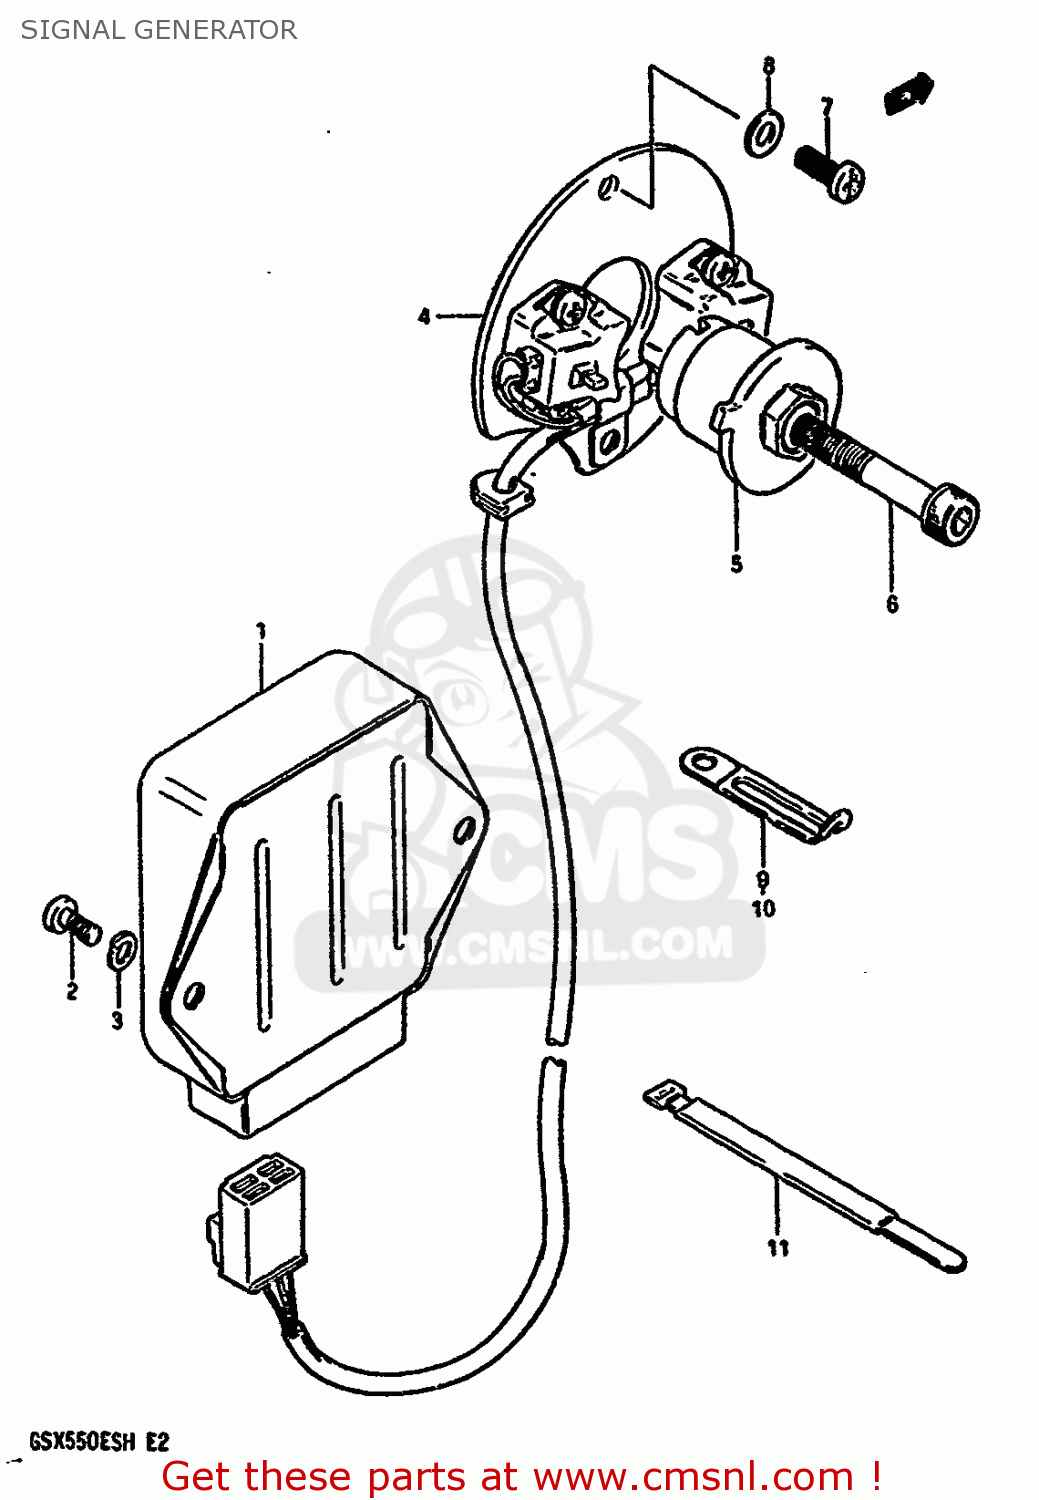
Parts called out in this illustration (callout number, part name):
1	IGNITER UNIT ASSEMBLY
2	SCREW 6X12
3	WASHER,LOCK
4	GENERATOR ASSY,SIGNAL
5	ROTOR,SIGNAL
6	BOLT
7	SCREW(5X12)
8	WASHER(5.5X10X0.8)
9	CLAMP L:35
10	CLAMP
11	CLAMP
